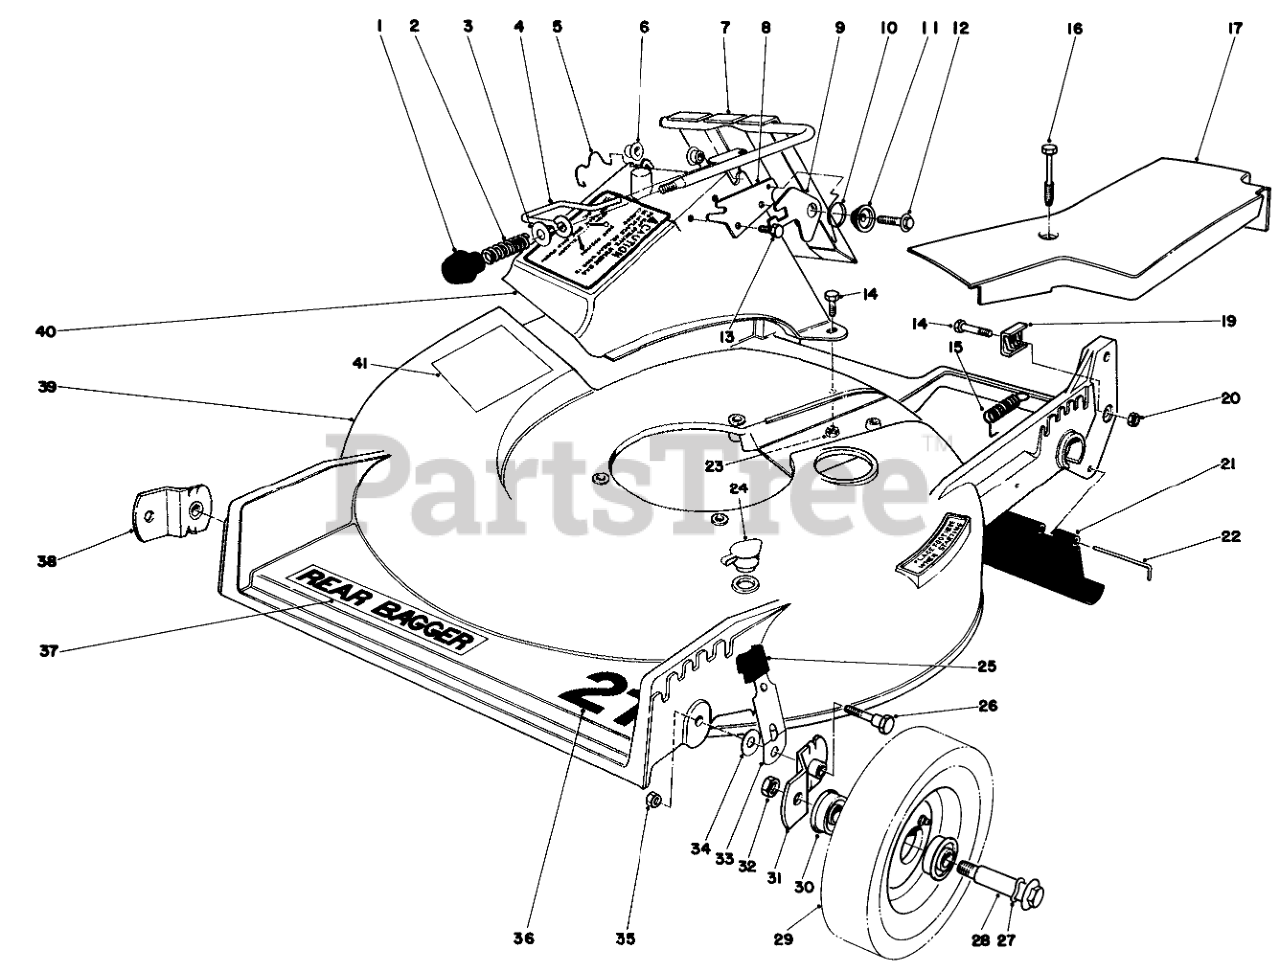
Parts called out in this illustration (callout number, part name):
2	COMPRESSION SPRING
3	WASHER
4	DOOR LATCH
5	DOOR RETAINER
6	BUSHING-NYLON
7	DOOR & HANDLE WA
8	DOOR LATCH PLATE
9	Latch Safety
10	TORSION SPRING
11	Latch Spacer
12	Screw
13	SCREW-HWH
14	SCREW-HH
15	IDLER SPRING
16	SCREW-HHFTF
17	Belt Cover
19	CLAMP-CABLE
20	NUT-JAM
21	SHIELD - TRAILING
22	Rod Shield
23	NUT-LOCK, NI
24	WASHOUT PLUG
25	KNOB-ARM
26	PIVOT SCREW
27	SPRING WASHER
29	Wheel & Tire Assembly (Incl. Ref. #30)
30	BEARING-BALL
31	PIVOT ARM ASM A
32	Nut
33	SPRING ARM ASM (R&S)
34	WASHER-PIVOT
35	Nut
36	Decal 21"
37	DECK DECAL
38	PIVOT ARM ASM B
39	Housing
40	DISCHARGE CHUTE B
41	Decal-Caution (French & Dutch)
